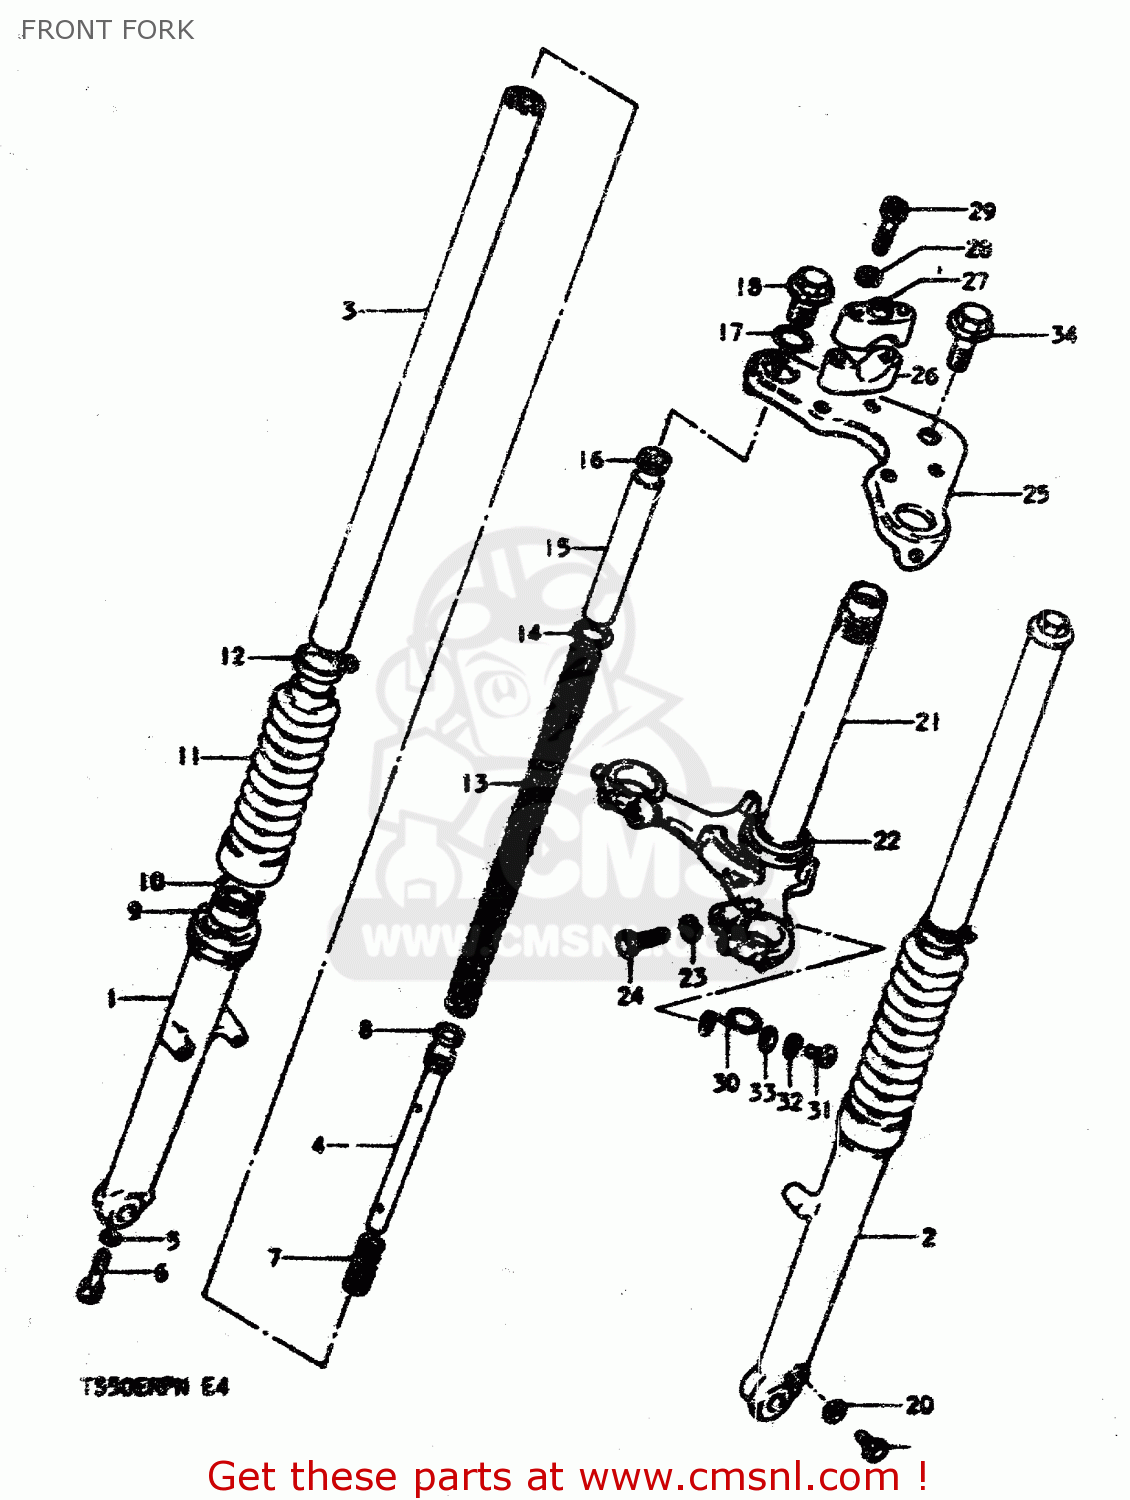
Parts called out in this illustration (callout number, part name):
1	TUBE, OUTER RH
2	TUBE, OUTER LH
3	TUBE, INNER
4	PIPE, SEAT
5	GASKET (NAS)
6	BOLT(8X27)
7	SPRING,REBOUND
8	RING,PISTON
9	OIL SEAL,FRONT FORK
10	RING,OIL SEAL STOPPER
11	BOOT
12	BAND
13	SPRING
14	JOINT,SPRING
15	SPACER,SPRING
16	NUT,FORK SPRING,UPPER
17	O-RING,FORK INNER TUBE
18	CAP
19	BOLT
20	GASKET,DRAIN,PLUG (NAS)
21	STEM, STEERING
22	RACE,STEERING OUTER LWR
23	LOCK WASHER
24	BOLT 10X30
25	STEM HEAD, STEERING
26	HOLDER, HANDLE LOWER
27	HOLDER,HANDLEBAR
28	LOCK WASHER
29	BOLT
30	CLIP
31	SCREW 6X12
32	LOCK WASHER
33	WASHER
34	BOLT
